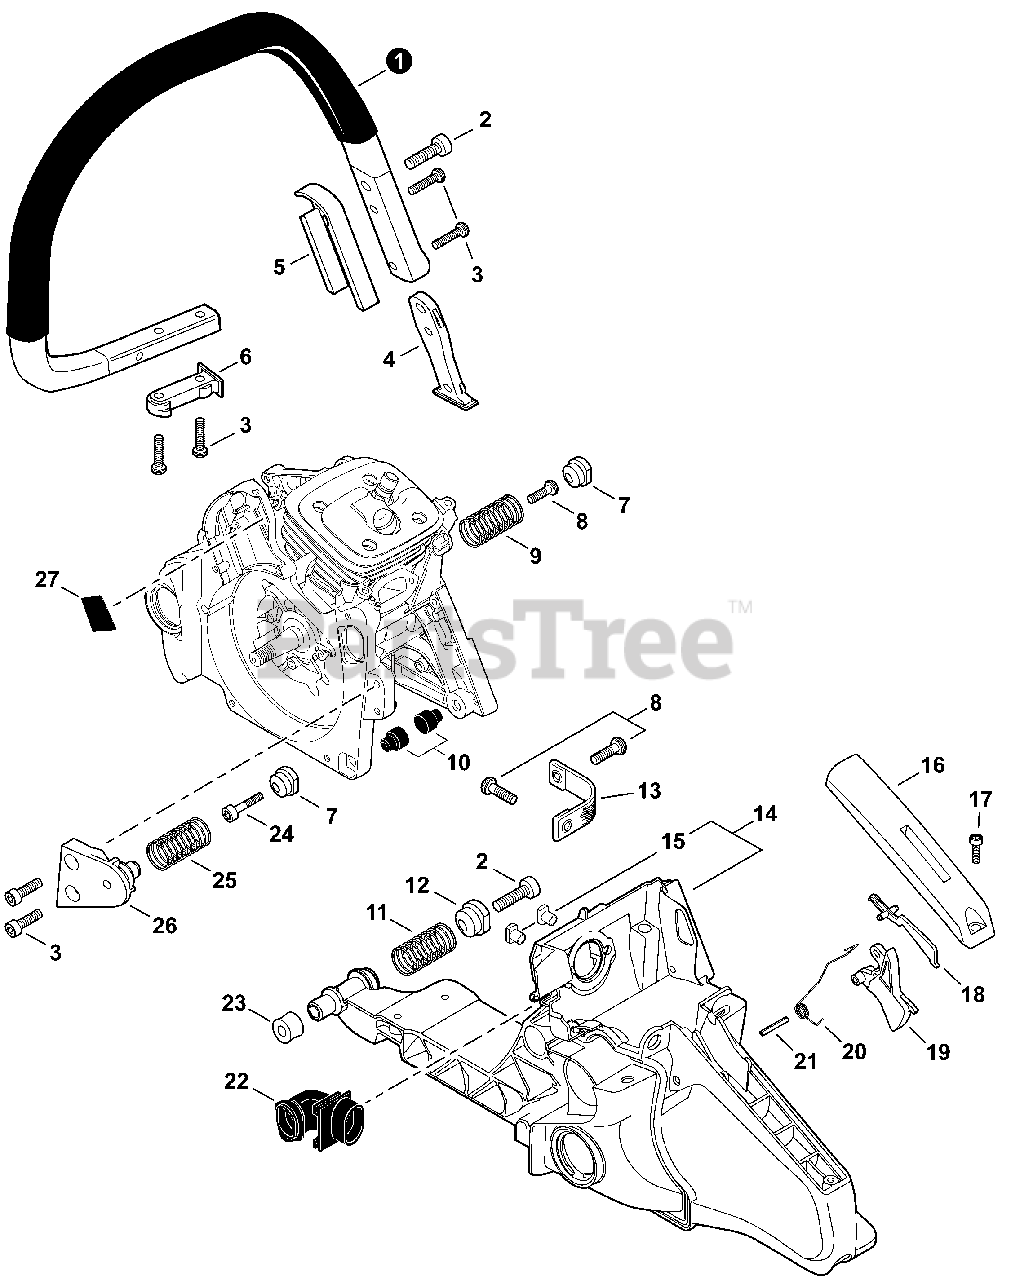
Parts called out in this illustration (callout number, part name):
1	HANDLE, FRONT
2	BOLT, TORX 6×20
3	BOLT, TORX 5×20
4	MOUNT, HANDLE
5	HOLDER, SPRING
6	MOUNT, HANDLE
7	HOLDER, SPRING Ø14.4
8	BOLT, TORX 5×16
9	SPRING, COMPRESSION Ø17×38.4×2.6
10	CUSHION
11	SPRING, COMPRESSION Ø20×40×3.3
12	HOLDER, SPRING Ø17
13	STRAP, SAFETY
14	HANDLE, REAR
16	COVER, HANDLE
17	BOLT, TORX 4×12
18	LEVER, THROTTLE LOCKOUT
19	TRIGGER, THROTTLE
20	SPRING, TORSION
21	PIN, SPRING 4×25 SUS
22	PIPE, AIR INTAKE
23	CUSHION 10
24	BOLT, TORX 5×25
25	SPRING, COMPRESSION Ø17×36.7×2.6
26	HOLDER, SPRING
27	CUSHION
